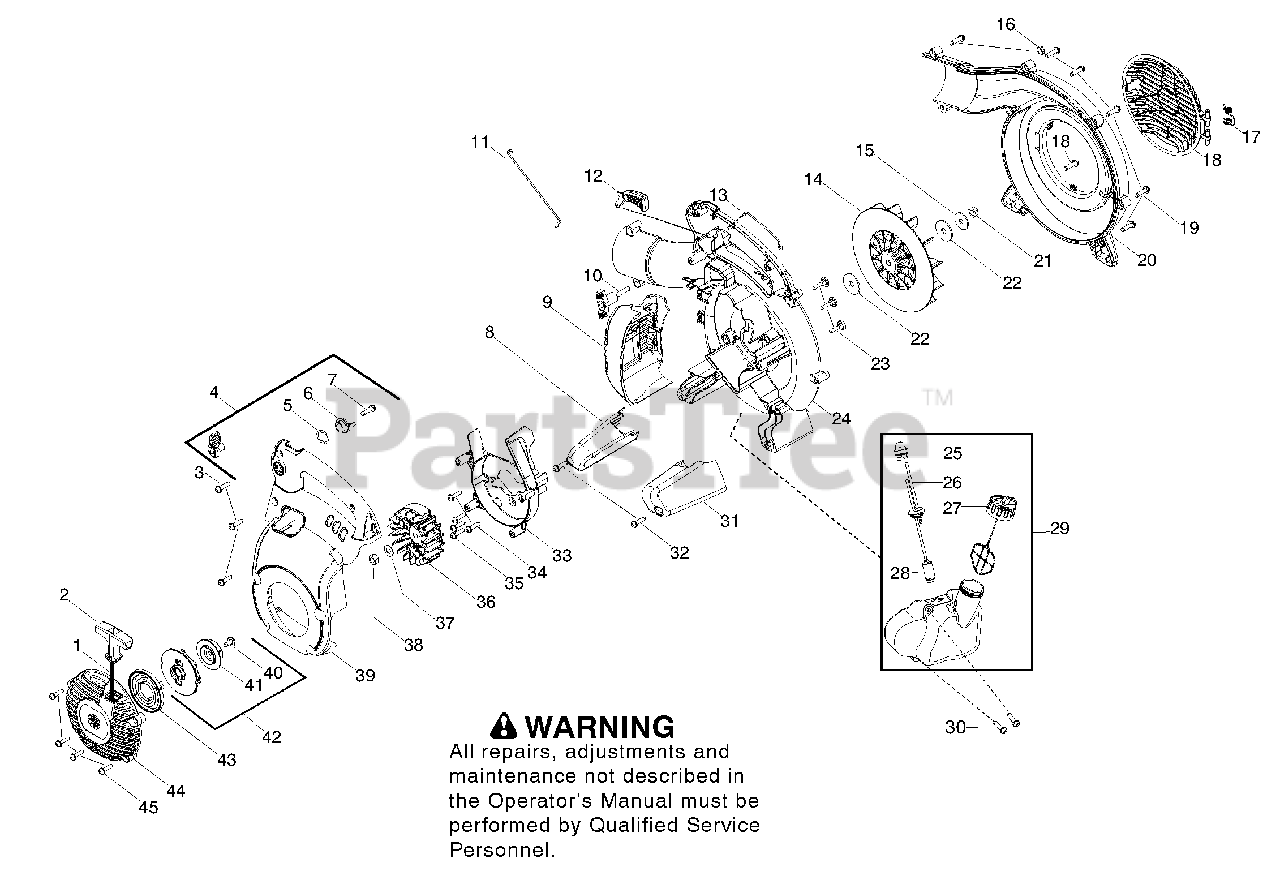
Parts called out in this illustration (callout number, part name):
1	Kit - Rope
2	Handle - Starter
4	Kit - Cruise Control
5	Washer - Wave
6	Ratchet - Cruise Control
8	Foot - Front Impact
9	Assy. - Muffler Guard
10	Assy - Blower Knob
11	Wire - Linkage
12	Trigger - Throttle
13	Wire - Handle Ground
14	Impeller
16	Nut - Blower Tube Knob
17	Spring - Vac Door
18	Cover - Vac Door
20	Assy - Outer scroll
21	Nut - Impeller
22	Washer - Impeller
24	Scroll - Inner
25	Bulb - Purge
26	Kit - Fuel line grommet
27	Assy - Fuel cap with retainer
28	Assy - Fuel pickup
29	Assy - Fuel tank
30	Screw - Fuel tank
31	Foot - Rear Impact
33	Scroll - Flywheel
35	Screw
36	Assy - Flywheel
38	Nut - Flywheel
39	Cover - Motor housing
42	Kit - Starter
43	Spring - Starter
44	Housing - Starter Cover
45	Screw
